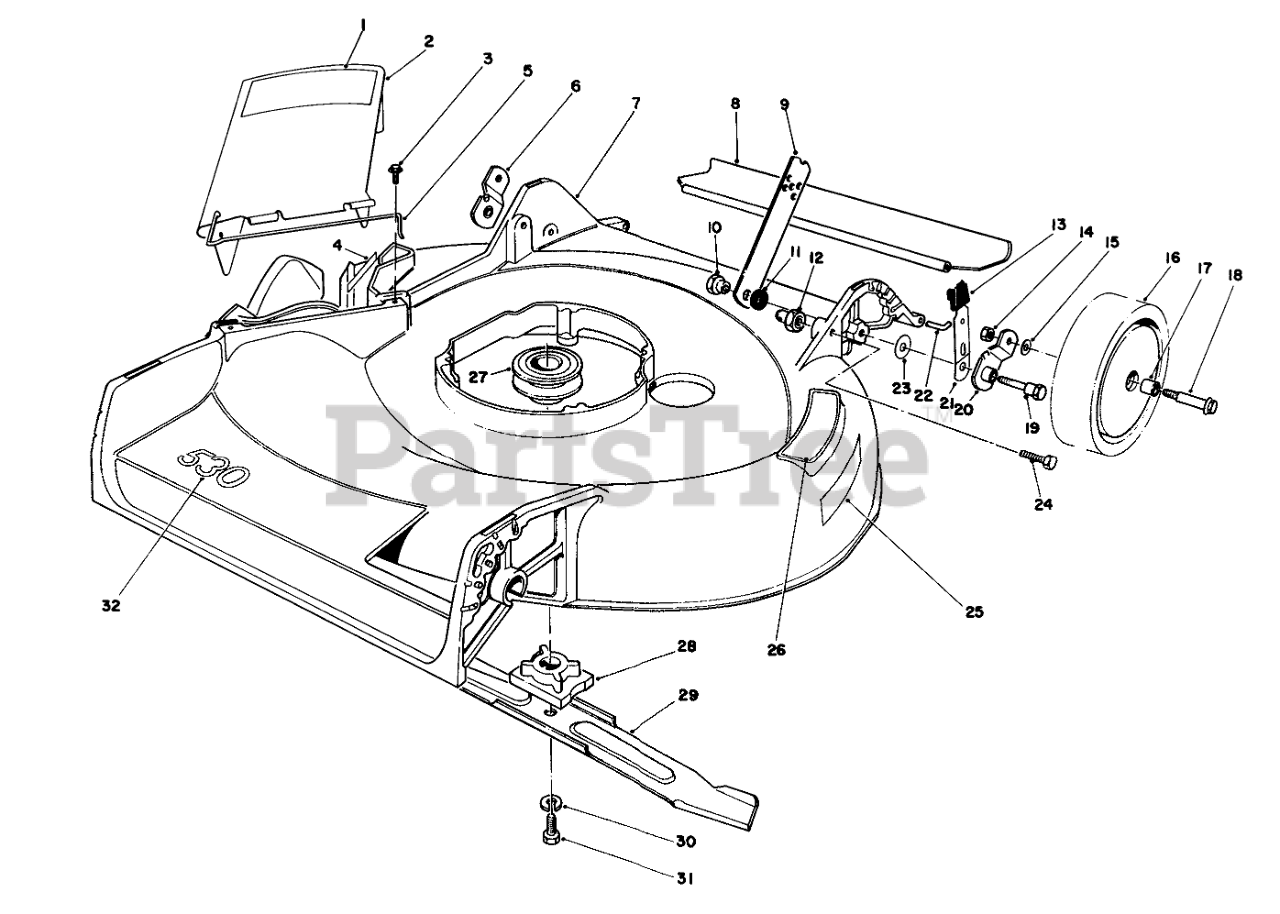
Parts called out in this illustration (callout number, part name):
1	Decal-Danger(French)
2	Deflector Assembly (Incl.Ref. #1 & 5)
3	SCREW-HWH
4	Decal-Danger
5	SPRING HINGE
6	Pivot Arm
7	Housing
8	REAR SAFETY SHIELD 21
9	HANDLE LATCH
10	HANDLE PIVOT NUT
11	SPACER
12	HANDLE PIVOT NUT
13	KNOB-ARM
14	NUT-LOCK
15	WASHER
16	Wheel & Tire Assembly (Incl. Ref. #17)
17	BUSHING
18	WHEEL BOLT
19	PIVOT SCREW
20	Pivot Arm
21	SPRING ARM ASM
22	SHIELD ROD
23	Washer
24	SCREW-HH
25	Decal-Step
26	STEP PAD DECAL
27	Pulley
28	BLADE RETAINER
29	Blade
30	Lockwasher
31	SCREW-HH
32	Decal-530
